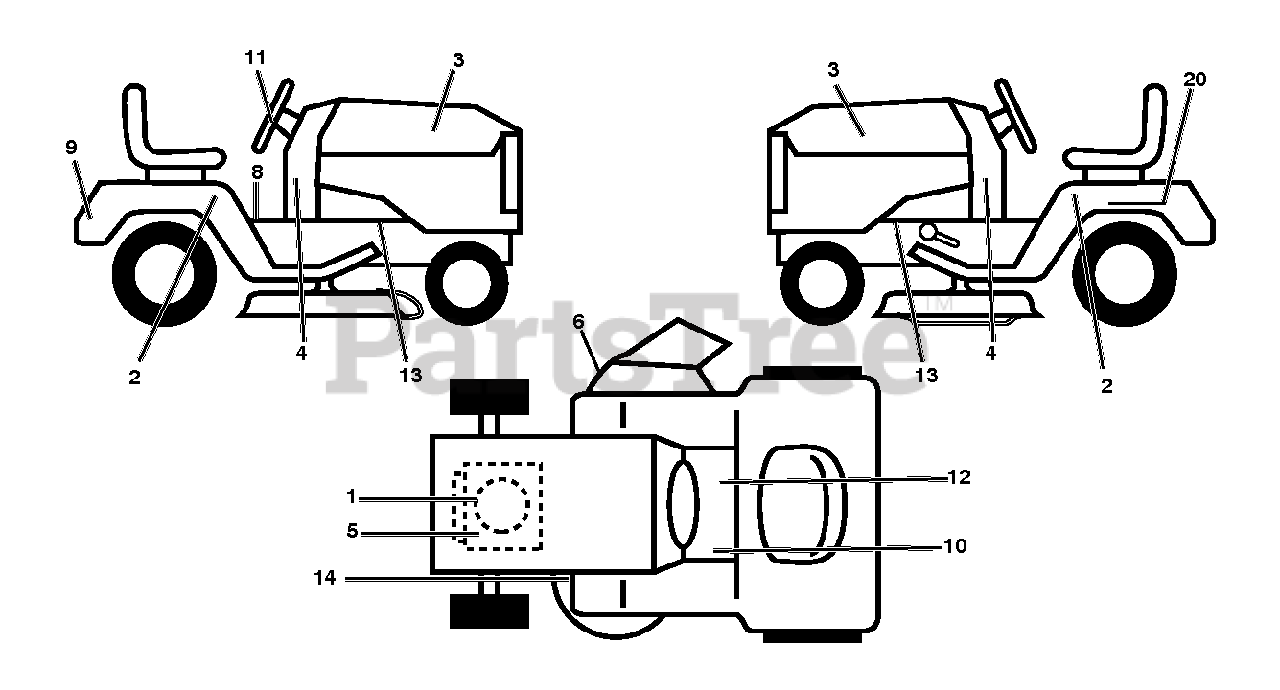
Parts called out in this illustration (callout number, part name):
2	DECAL.FEND.RH/LH.SET.6S.POULAN
3	DECAL.HOOD.ALPHA.RH/LH.POULAN
5	DECAL.ENGINE.WARNING
6	DECAL.WARN.DFLCTR/CTFNGR.SRD.
8	DECAL.READ.OWN.MAN.SYMBOL.LT
9	DECAL.FEND.POULAN.2010
10	DECAL.FNDR.SDLE.BRAKE.CLUTCH.6
11	DECAL.WHEEL.STRG.STDHRS.POULAN
12	DECAL.PARKING.BRAKE.SADDLE.LT
13	DECAL.CHASSIS.HOT.MUFFLER
14	DECAL.V.BELT.30"
20	DECAL BTRY SYMBOLS
